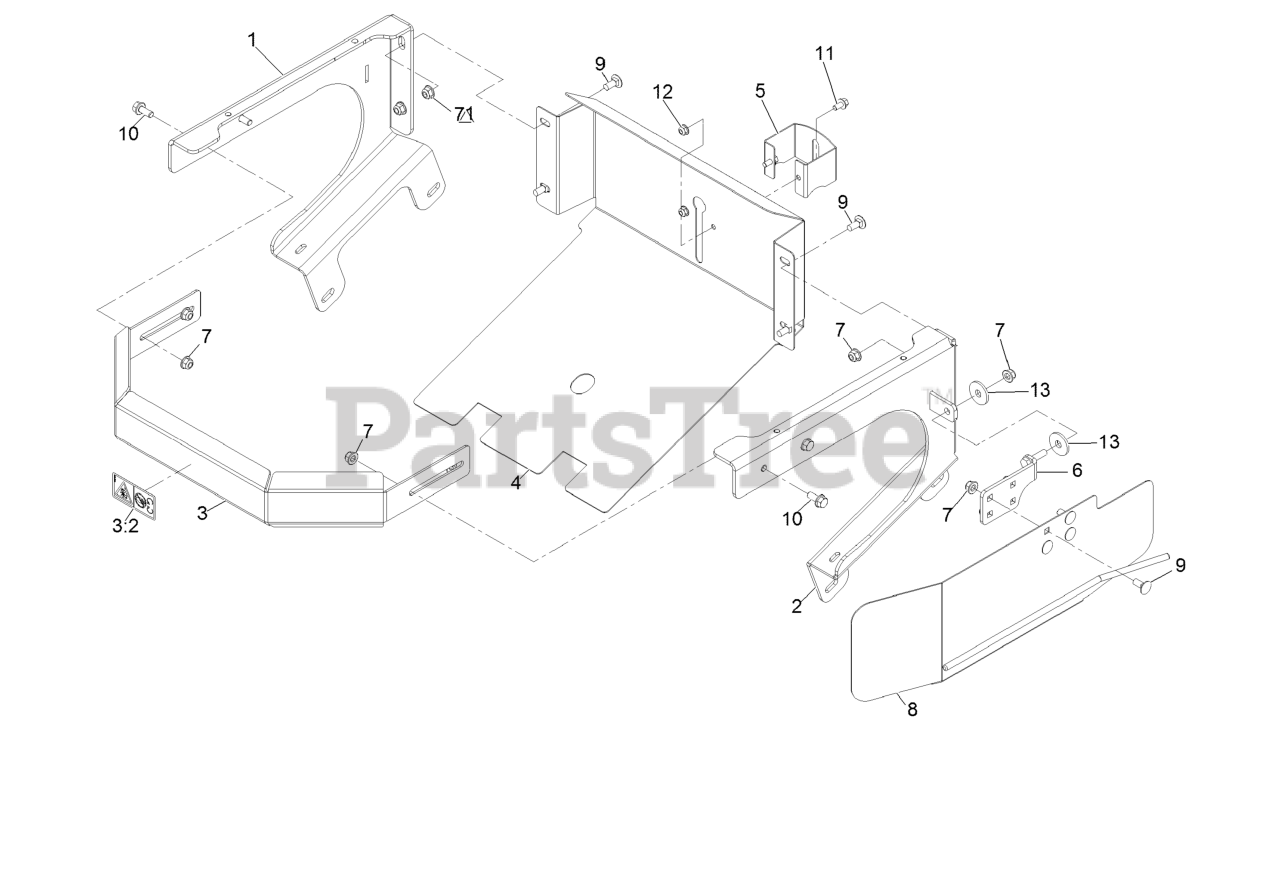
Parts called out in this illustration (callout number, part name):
1	FRAME-HOPPER, RH
2	FRAME-HOPPER, LH
3	BUMPER-FRONT
3:2	Decal-Dismemberment Hazard
4	BACKSHIELD, AE HOPPER
5	BRACKET-CABLE, HOPPER
6	MOUNT-DEFLECTOR
7	Nut-Hex Flange
8	DEFLECTOR-ZPLUG
9	SCREW-CARR
10	SCREW-HHF
11	SCREW-HHF
12	Nut-Hex Flange
13	WASHER
